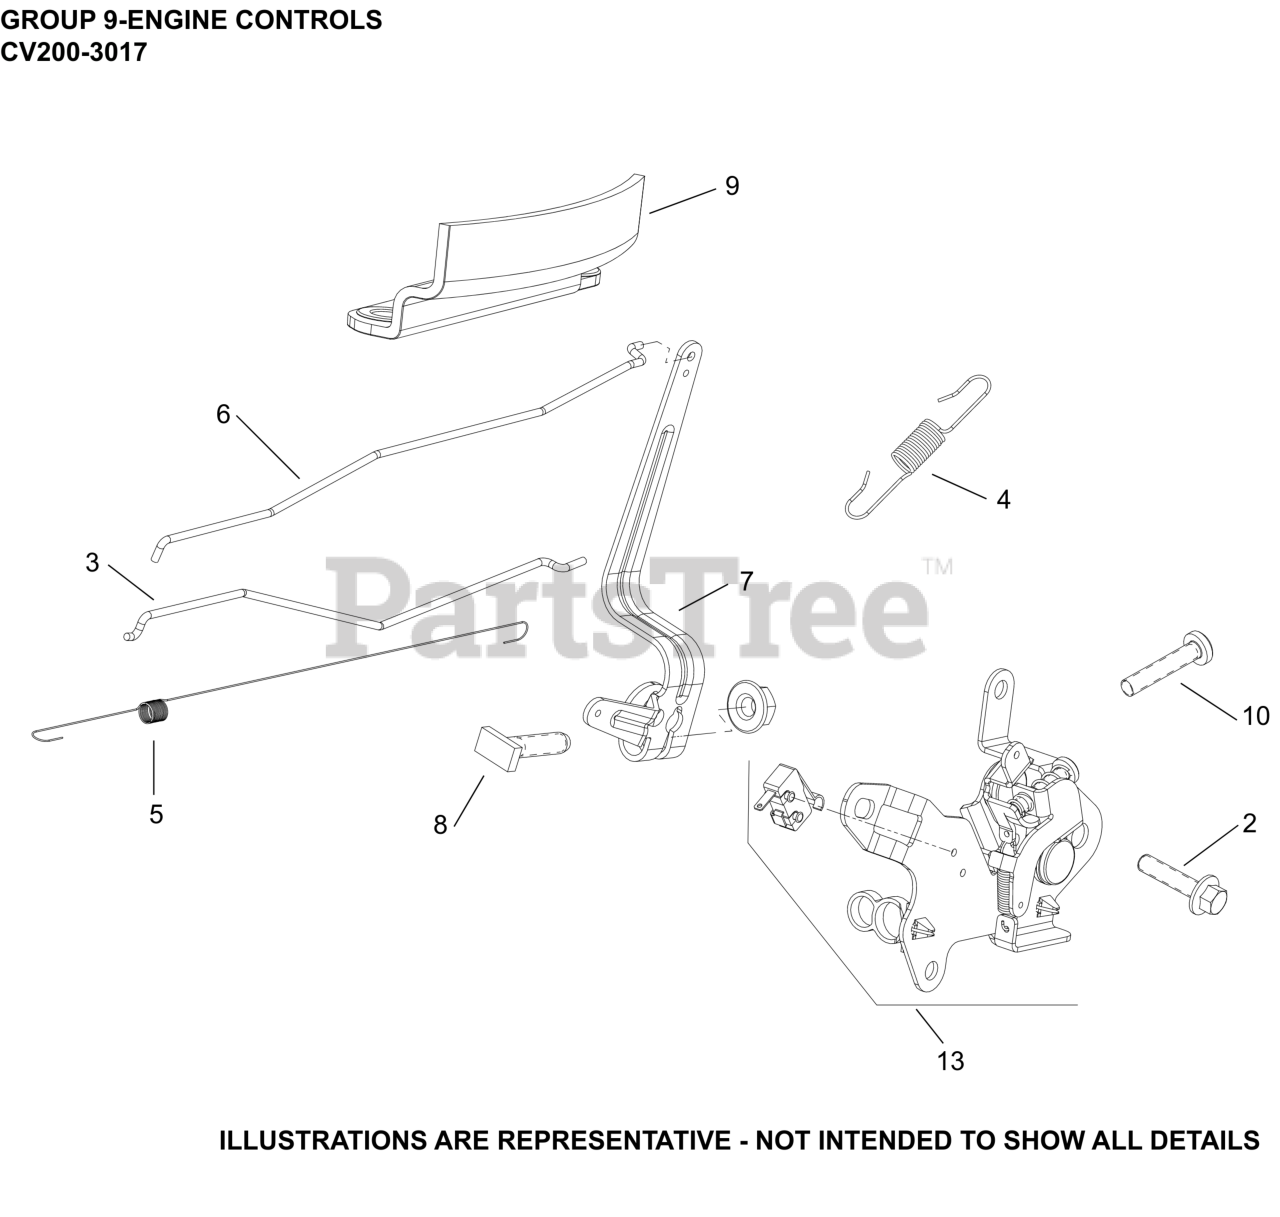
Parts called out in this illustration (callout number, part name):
2	SCREW, (M5) HEX FLANGE
3	LINKAGE, CHOKE
4	SPRING, GOVERNOR
5	SPRING, LINKAGE
6	LINKAGE, GOVERNOR
7	LEVER, GOVERNOR
8	SCREW, RECTANGLE HEAD (M6)
9	GUARD, FINGER
10	SCREW, SPEED ADJUSTING
13	CONTROL ASSEMBLY, REMOTE VARIABLE SPEED
